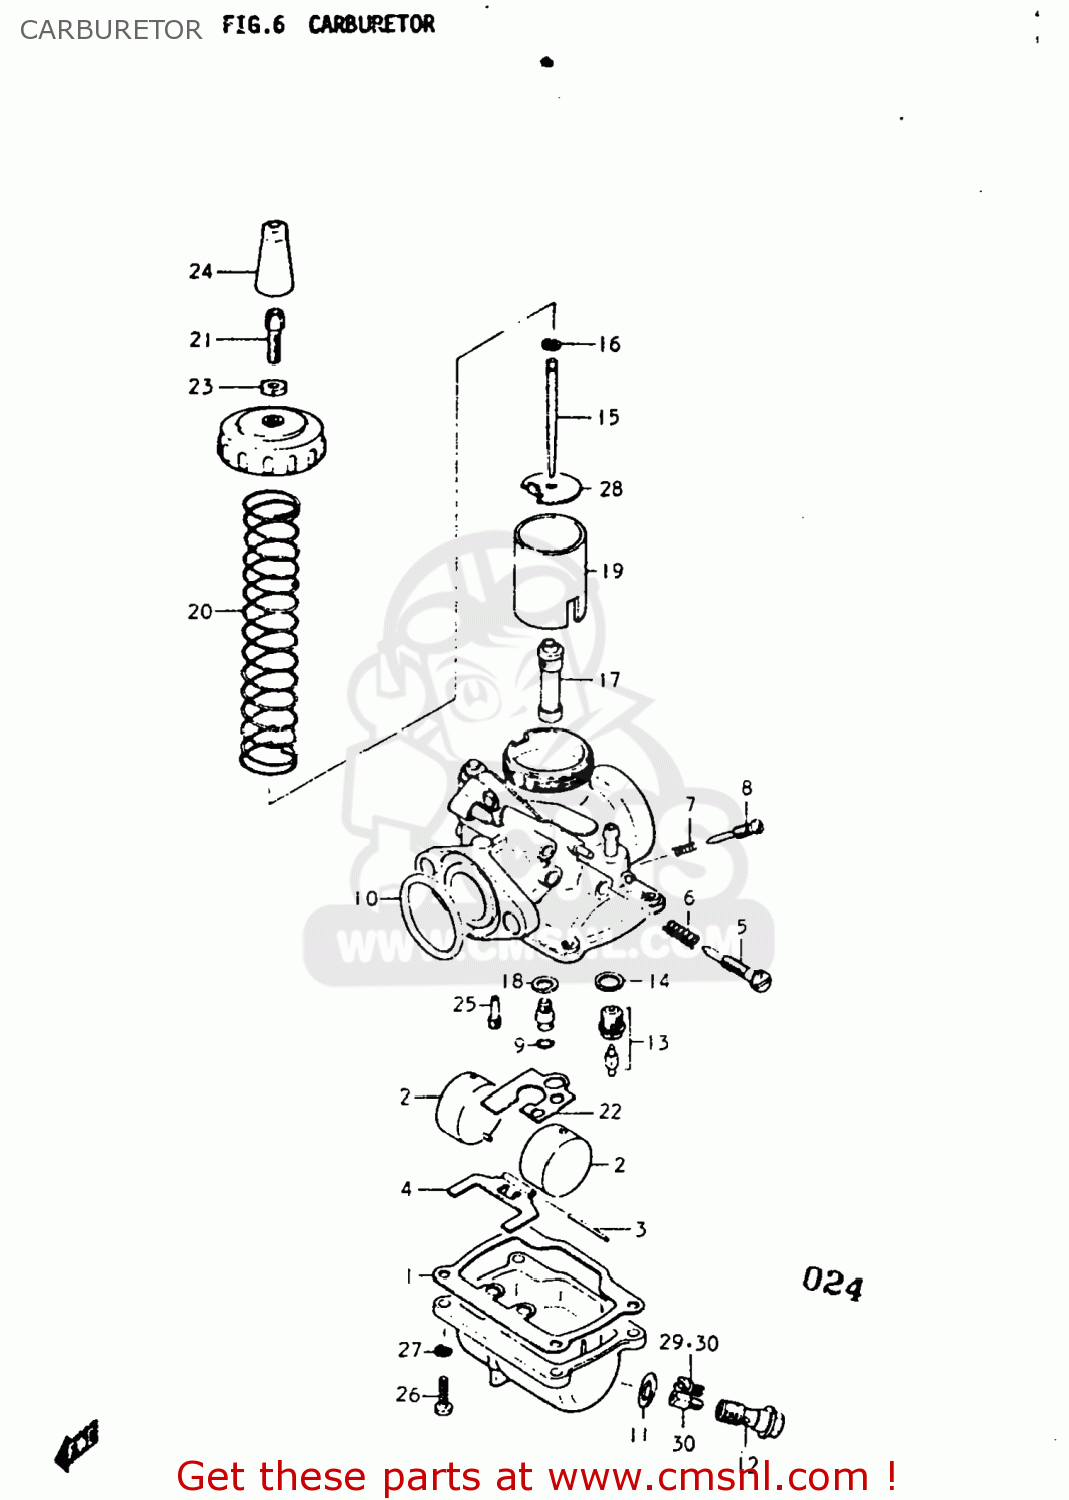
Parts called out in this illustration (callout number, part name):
1	CARBURETOR ASSEMBLY
2	FLOAT
3	PIN,FLOAT
4	ARM,FLOAT
5	SCREW,THROTTLE STOP
6	SPRING,THROTTLE SCREW
7	SPRING
8	SCREW,PILOT AIR
9	O RING
10	O RING
11	WASHER
12	HOLDER
13	VALVE ASSY,NEEDLE
14	GASKET,VALVE SEAT (NAS)
15	NEEDLE,JET
16	CLIP
17	JET,NEEDLE
18	WASHER
19	VALVE,THROTTLE
20	SPRING, THROTTLE VALVE
21	ADJUSTER,CABLE
22	PLATE
23	NUT
24	CAP
25	JET
26	SCREW
27	LOCK WASHER
28	SEAT,THROTTLE VALVE SPRING
29	JET
30	JET
